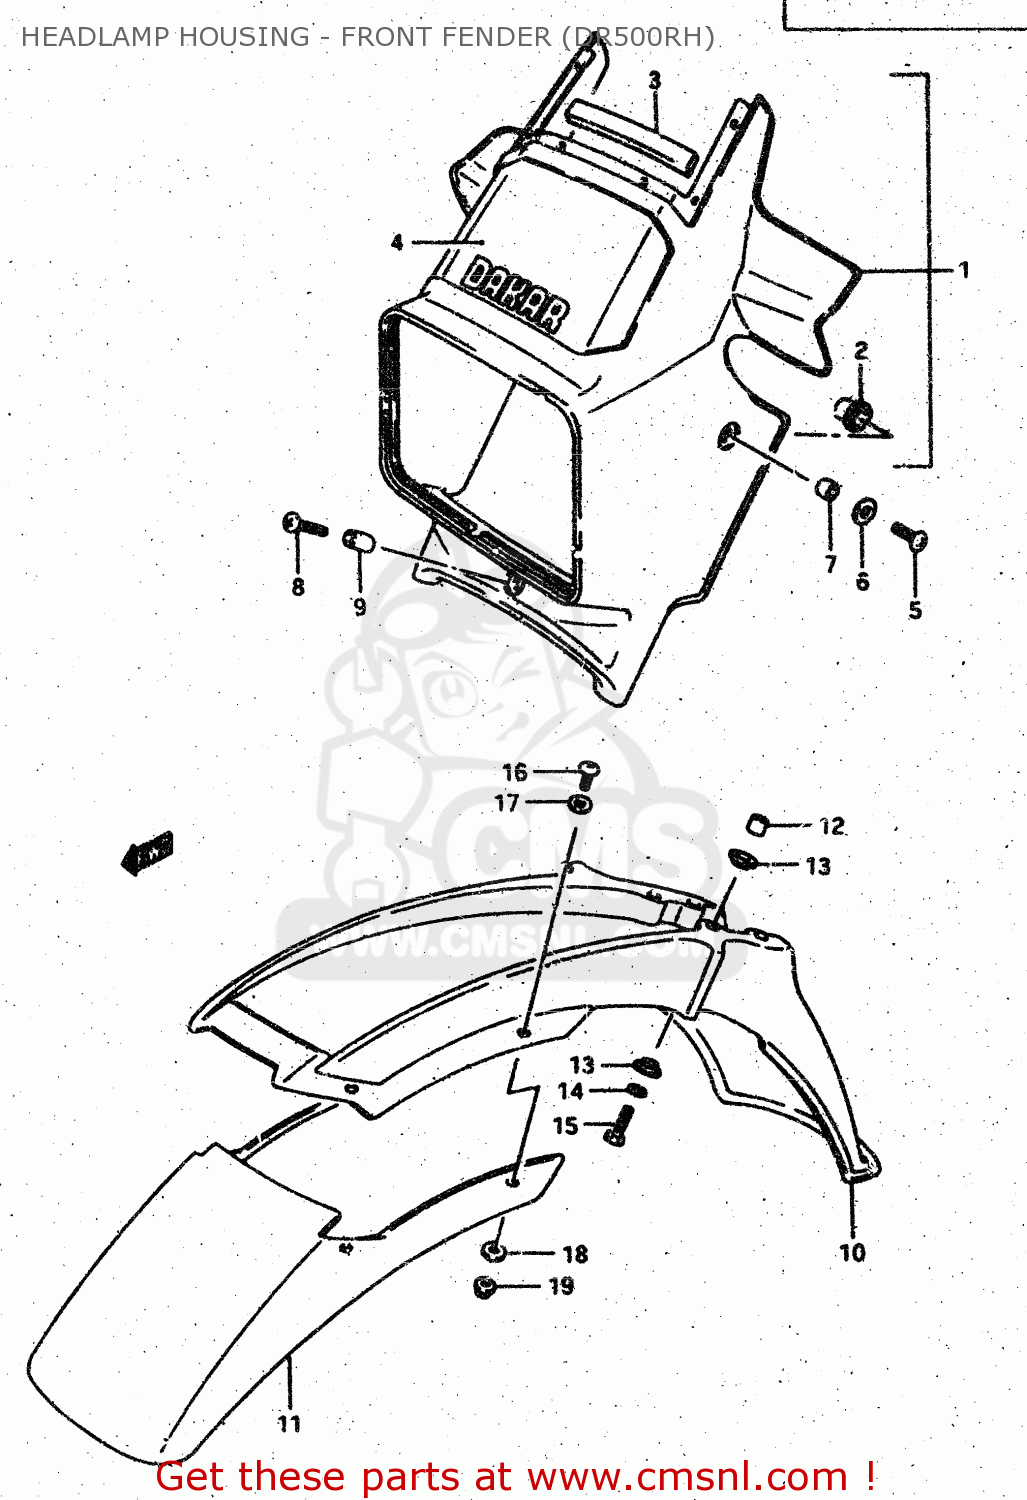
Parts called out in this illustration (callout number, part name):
1	COVER, HEADLAMP (WHITE)
2	BUSH, SIDE (WHITE)
3	CUSHION,HEADLAMP COVER
4	TAPE, HEADLAMP COVER
5	SCREW
6	WASHER
7	SPACER
8	SCREW, LOWER
9	SPACER, COVER LOWER
10	FENDER, FRONT REAR (WHITE)
11	FENDER, FRONT (BLUE)
12	SPACER(6.1X9X7.5)
13	WASHER
14	WASHER,LOCK
15	BOLT
16	SCREW
17	WASHER,COVER,FRONT
18	WASHER (6.7X16X1.8)
19	NUT
